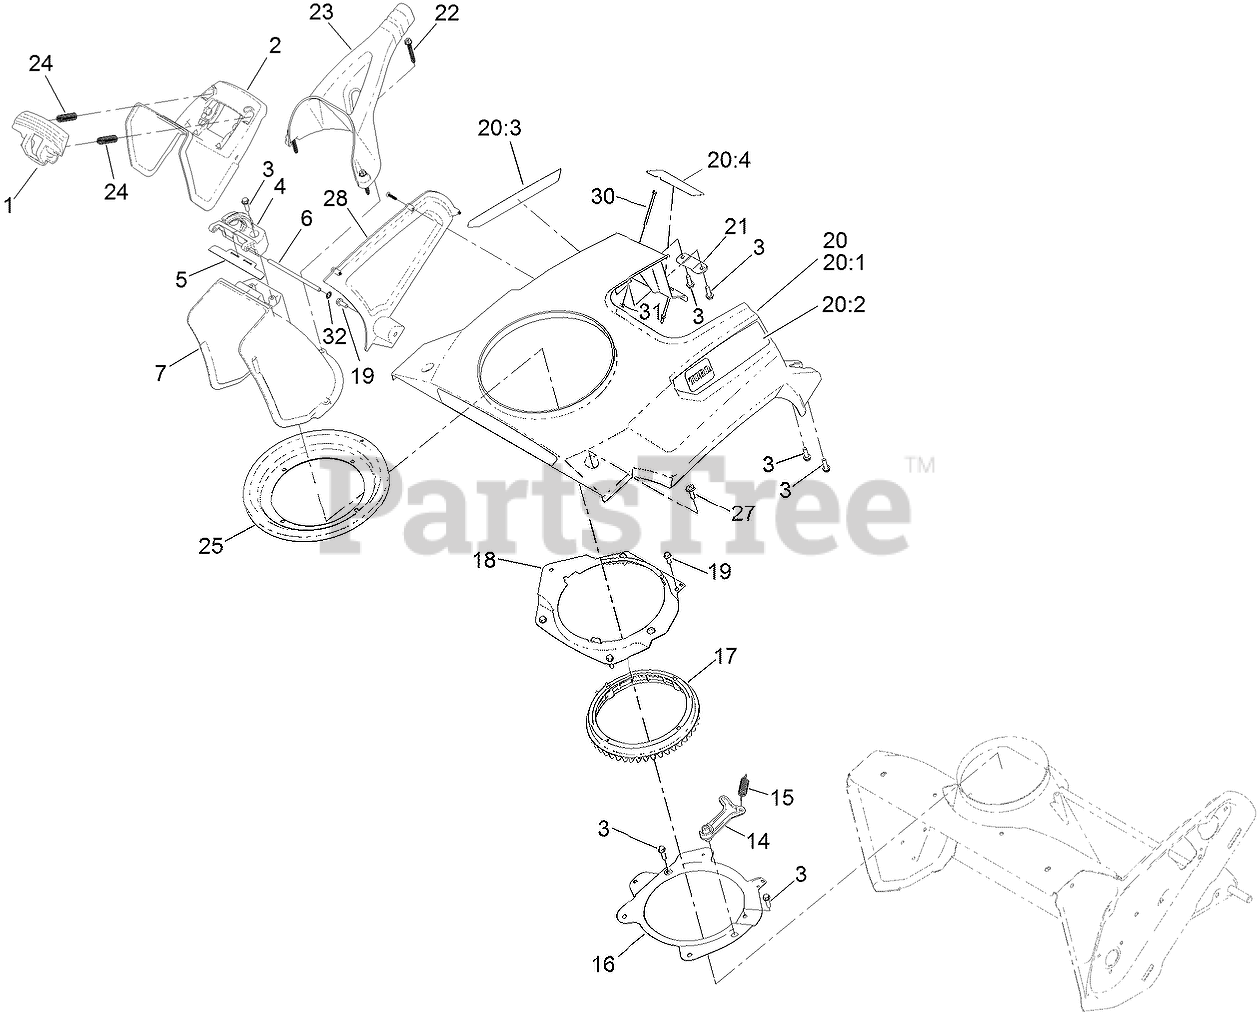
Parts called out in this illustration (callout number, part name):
1	TRIGGER-DEFLECTOR
2	DEFLECTOR-CHUTE, CE
3	SCREW-HWH
4	HINGE-RATCHET, DEFLECTOR
5	SEAL-DEFLECTOR
6	HINGE PIN-DEFLECTOR
14	PAWL-DETENT
15	SPRING-EXTENSION
16	RING-SUPPORT, CHUTE
17	RING-CHUTE, DETENT
18	RETAINER-RING, CHUTE
19	SCREW-HWH
20	SHROUD ASM, W/DECALS
20:1	SHROUD ASM, W/ARTWORK
20:2	DECAL-SHROUD LH
20:3	DECAL-SHROUD RH
20:4	DECAL-ENGINE, ELECTRIC START
21	RETAINER-SHROUD
22	SCREW-HWH, PLASTITE
23	HANDLE-CHUTE
24	SPRING-COMPRESSION
25	SEAL-RING, CHUTE
27	SCREW-PPH
28	COVER-SIDE
30	SCREW-HWH
31	NUT-HEX
32	RING-RETAINING
